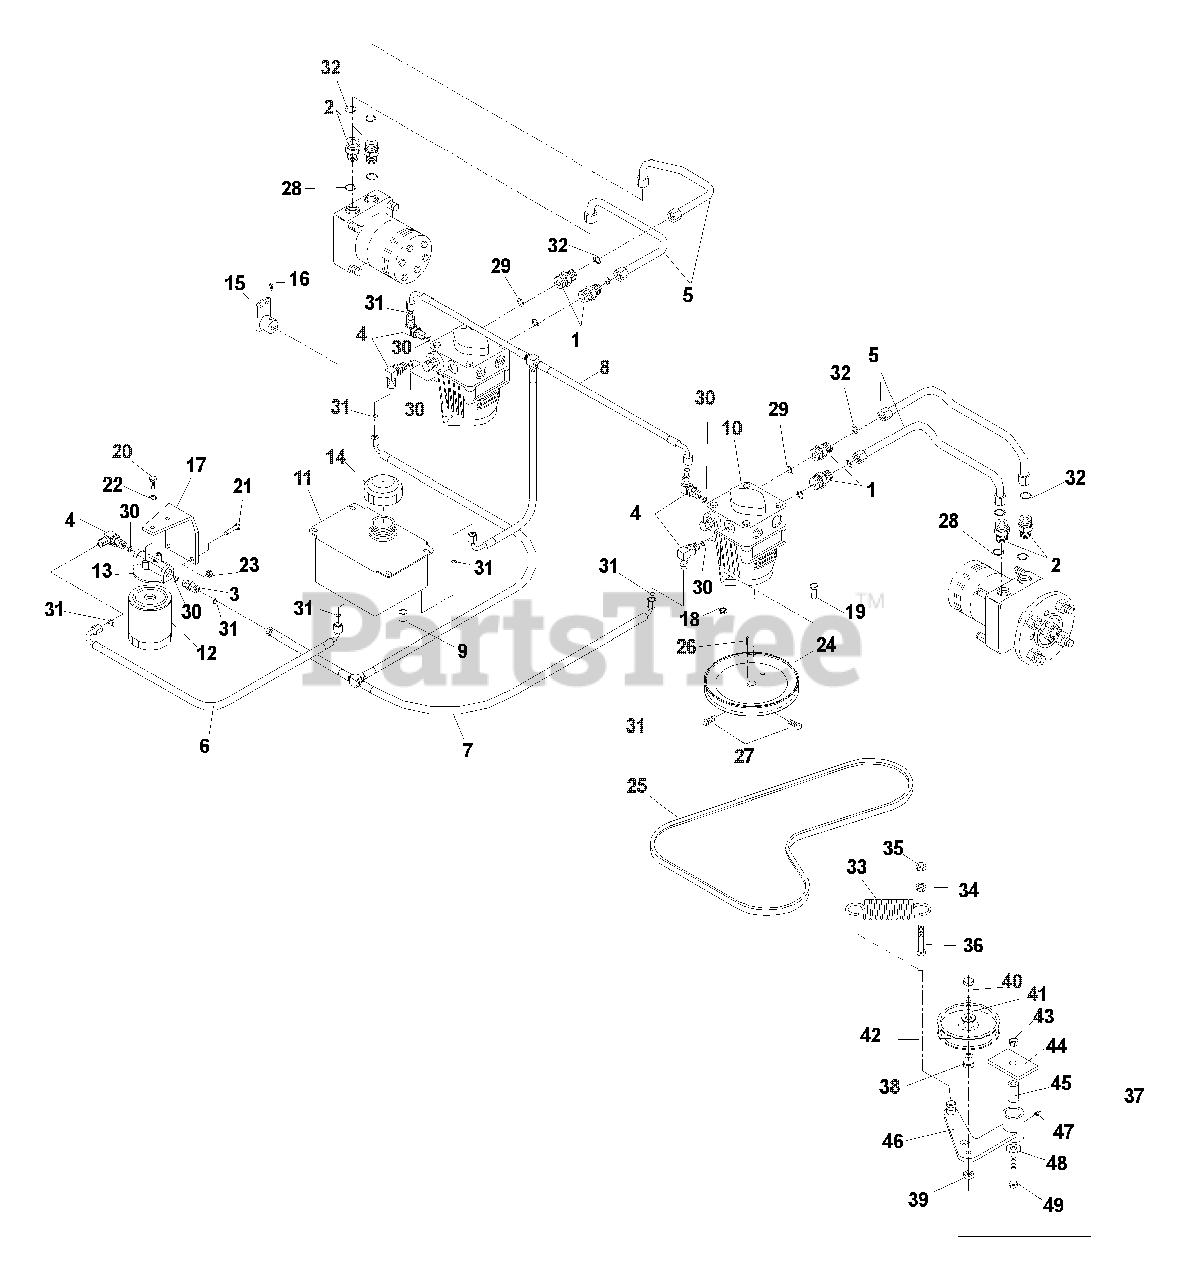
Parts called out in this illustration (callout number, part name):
1	FITTING, STRAIGHT, F6400-8-8-0
2	FITTING, STRAIGHT
3	FITTING, F6400-6-6-0
4	FITTING, 90°, F6801-6-6-0
5	HYDRAULIC LINE
7	"T" ASSEMBLY
8	"T" ASSEMBLY
10	PUMP
13	FILTER HEAD
14	CAP HYDRAULIC RESERVOIR
15	PUMP LEVER
16	V-POINT, 5/16C X 5/8
17	BRACKET, OIL FILTER
18	NUT, 3/8C, LOCK
19	HFCS, 3/8C X 1
20	HCS 1/4C X 5/8
21	HCS 1/4C X 3/4
22	LOCKWASH, 1/4
23	NUT, 1/4C, NYLOC
24	PULLEY, PUMP
25	BELT, PUMP
26	KEY, 5MM SQ X 25MM
27	SET SCREW, 5/16C X 5/8
28	"O" RING, 3/4
29	"O" RING, 1/2
30	"O" RING, 3/8
31	"O" RING FLARE, 3/8
32	"O" RING FLARE, 1/2
34	NUT, 3/8C, WHIZ
35	NUT, 3/8C, NYLOC
36	HCS 3/8C X 2
37	IDLER ARM ASSEMBLY
38	IDLER FLANGE BUSHING
39	NUT, 3/8C, CENTERLOCK
40	HCS, 3/8C X 1 3/4
41	WASHER, 3/8
42	IDLER PULLEY
43	NUT, 1/2C, NYLOC
44	SUPPORT PLATE
45	PIVOT BUSHING
46	IDLER ARM
47	ZERK
48	WASHER, 1/2
49	HCS, 1/2C X 3 1/4, GR5
